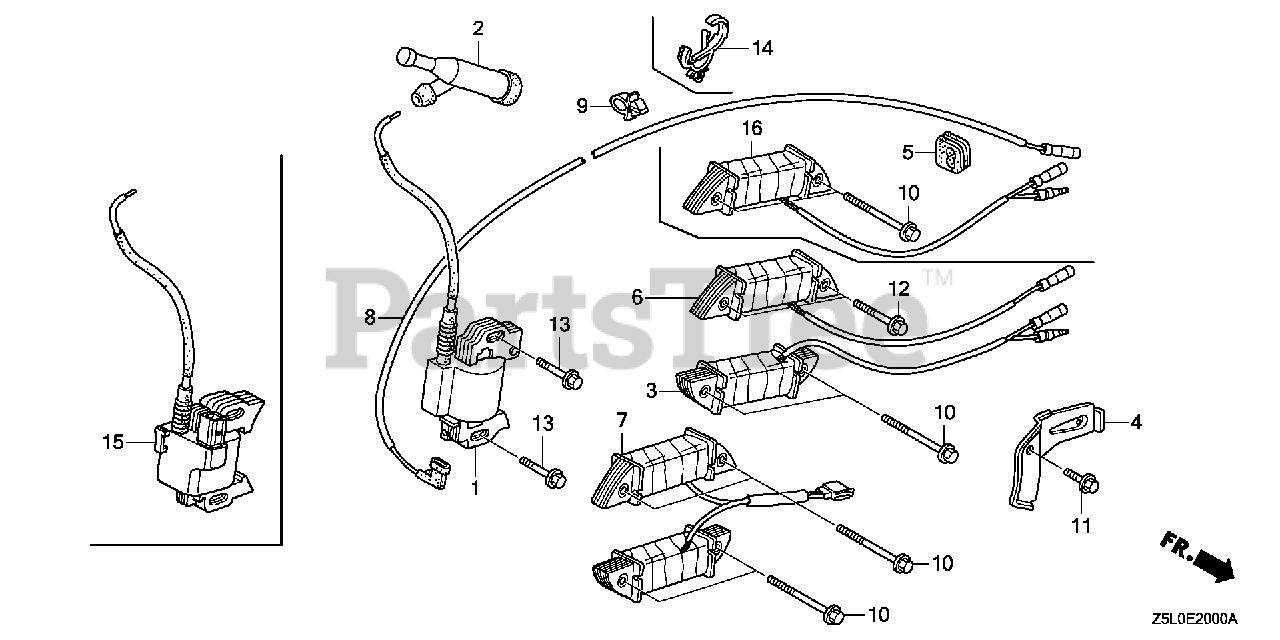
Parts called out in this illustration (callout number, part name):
2	CAP ASSY., NOISE SUPPRESSOR (Honda Code 3526837). (NICHIWA Y-EZ RTFM256)
3	COIL ASSY., LAMP (12V/25W)
4	CLAMP, WIRE
5	GROMMET, WIRE
6	COIL ASSY., CHARGE (1A)
10	BOLT, FLANGE (6X40)
11	BOLT, FLANGE (6X12) (CT200)
12	BOLT, FLANGE (6X35)
13	BOLT, FLANGE (6X28) (CT200) Use up to Engine SN 1530314.
15	COIL ASSY., IGNITION
